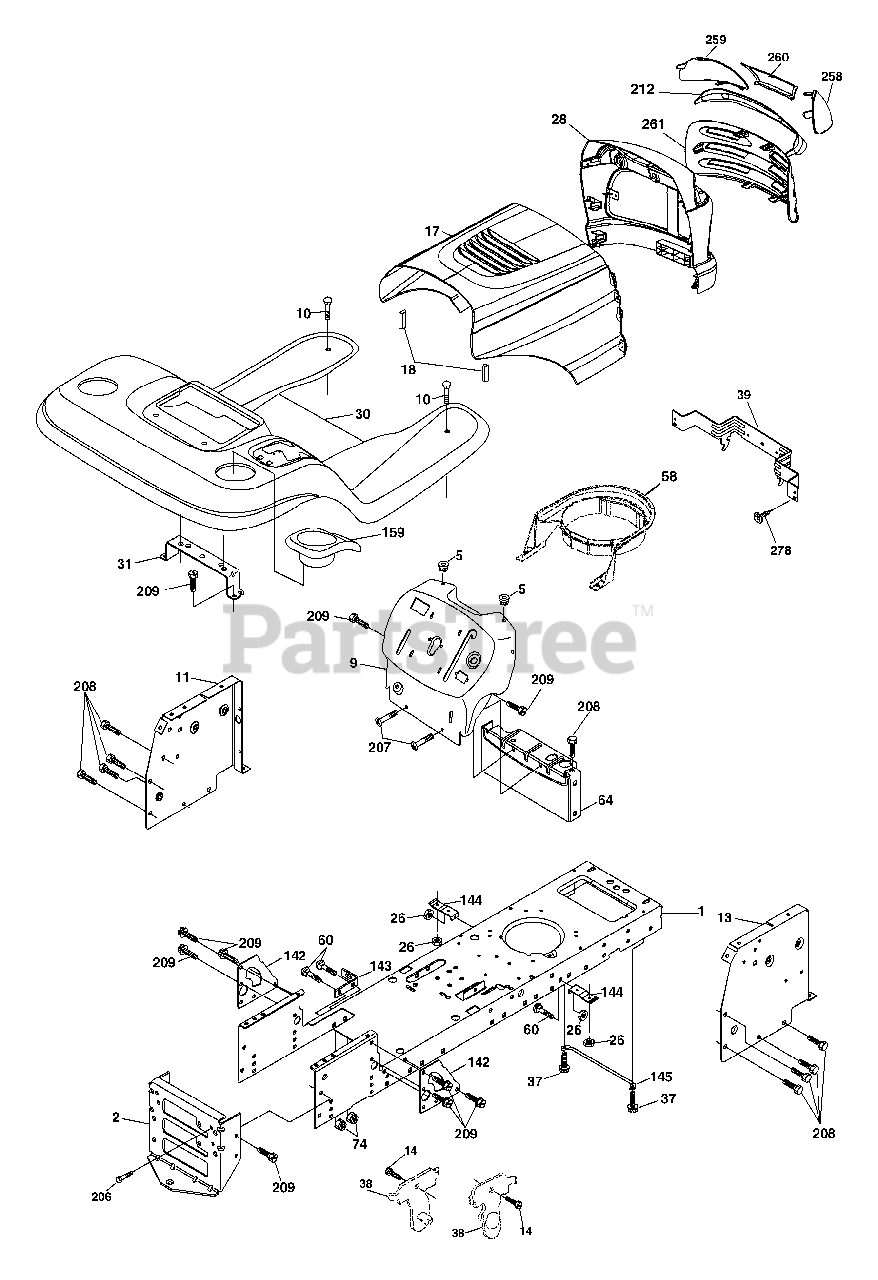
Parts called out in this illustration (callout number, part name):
1	Chassis Stamping
9	Dashboard
10	Bolt Rdhd Sqnk 3/8-16 unc x 1
11	Panel Dash Lh
13	Panel Dash Rh
14	Screw Thdrol 3/8-16 x 1/2
17	Hood
18	Bumper Hood
20	Plate Battery
23	Bushing Snap
26	Nut Lock w/Insert 3/8-16 unc
28	Grille Lens Asm
30	Fender
37	Screw Thdrol 5/16-18 x 1/2
38	Bracket Asm Pivot Mower Rear
39	Bracket Pivot Hood
60	Bolt RDHD SQNK 3/8-16 x 3/4
64	Dash Lower Stlt
74	Nut Crownlock 3/8-16
142	Plate Reinforcement Stlt
143	Bracket Swaybar Chassis
144	Bracket Ft Rest
145	Rod Pivot Chassis Hood
159	Cupholder
206	Bolt Shoulder 5/16-18 TT
207	Screw Thdrol 5/16-18 x 1/2 TYTT
208	Screw Thdrol 3/8-16 x 1/2 Ty-TT
209	Screw 3/8-16 x 3/4
212	Insert Lens Reflect
219	Screw 5/16-18 x 3/4
258	Lens RH
259	Lens LH
260	Cover Lens
261	Insert, Grille
278	Screw 10 x 3/4 Single Lead-Hex
